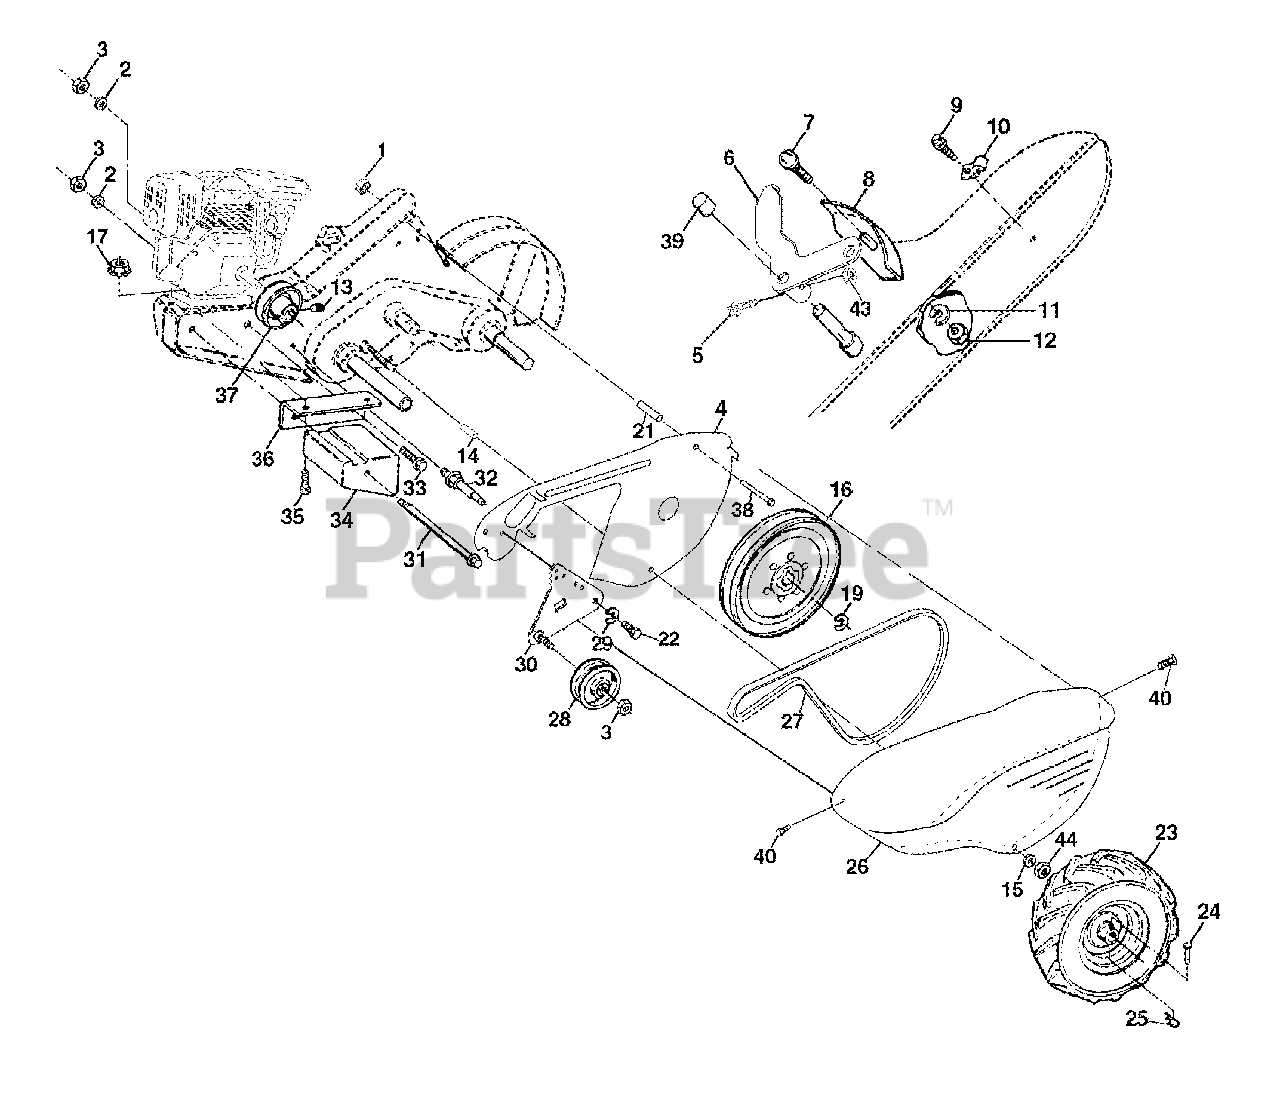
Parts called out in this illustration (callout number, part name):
1	Nut, Keps 5/16-18
2	Washer, Lock 3/8
3	Nut, Hex 3/8-16
4	Shield Inner Belt Guard
5	Screw Shift Lever
6	Lever, Shift
7	Bolt, Carriage 1/4-20 x 1/2 Gr. 5
8	Plate, Shift Indicator
9	Screw, Hex, Washer Head, Slotted #10-24 x 1/2
10	Clip
11	Washer, Lock 1/4
12	Nut, Hex 1/4-20
13	Screw, Set, Hex 5/16-18 x 3/8
14	Spacer, Split 0.327 x 0.42 x 1.220
15	Washer 11/32 x 11/16 x 16 Ga.
16	Sheave, Transmission
17	Locknut, Hex Flange 5/16-18
19	Ring, Retainer
21	Spacer, Split 0.327 x 0.42 x 2.09
22	Bolt Fin Hex 5/16-24 x 1/2
23	Tire
23	Rim
23	Tire Valve
24	Rivet, Drilled
25	Clip, Hairpin
26	Guard, Belt
27	Belt, V
28	Pulley, Idler
29	Ring, Klip
30	Bracket, Idler
31	Bolt, Hex 5/16-16 x 12
32	Shaft, Idler Arm
33	Bolt, Hex 3/8-16 x 1
34	Counterweight, L. H.
35	Bolt, Hex 5/16-18 x 1-1/2
36	Bracket, Reinforcement, L. H.
37	Sheave, Engine
38	Bolt Fin Hex 5/16-18 x 2-3/4
39	Cap, Plunger Blk
40	Screw Hex Wsh. SLT #10-24 x .50
43	Nut Lock #10-24
44	Nut Lock Hx W/Ins 5/16-18
